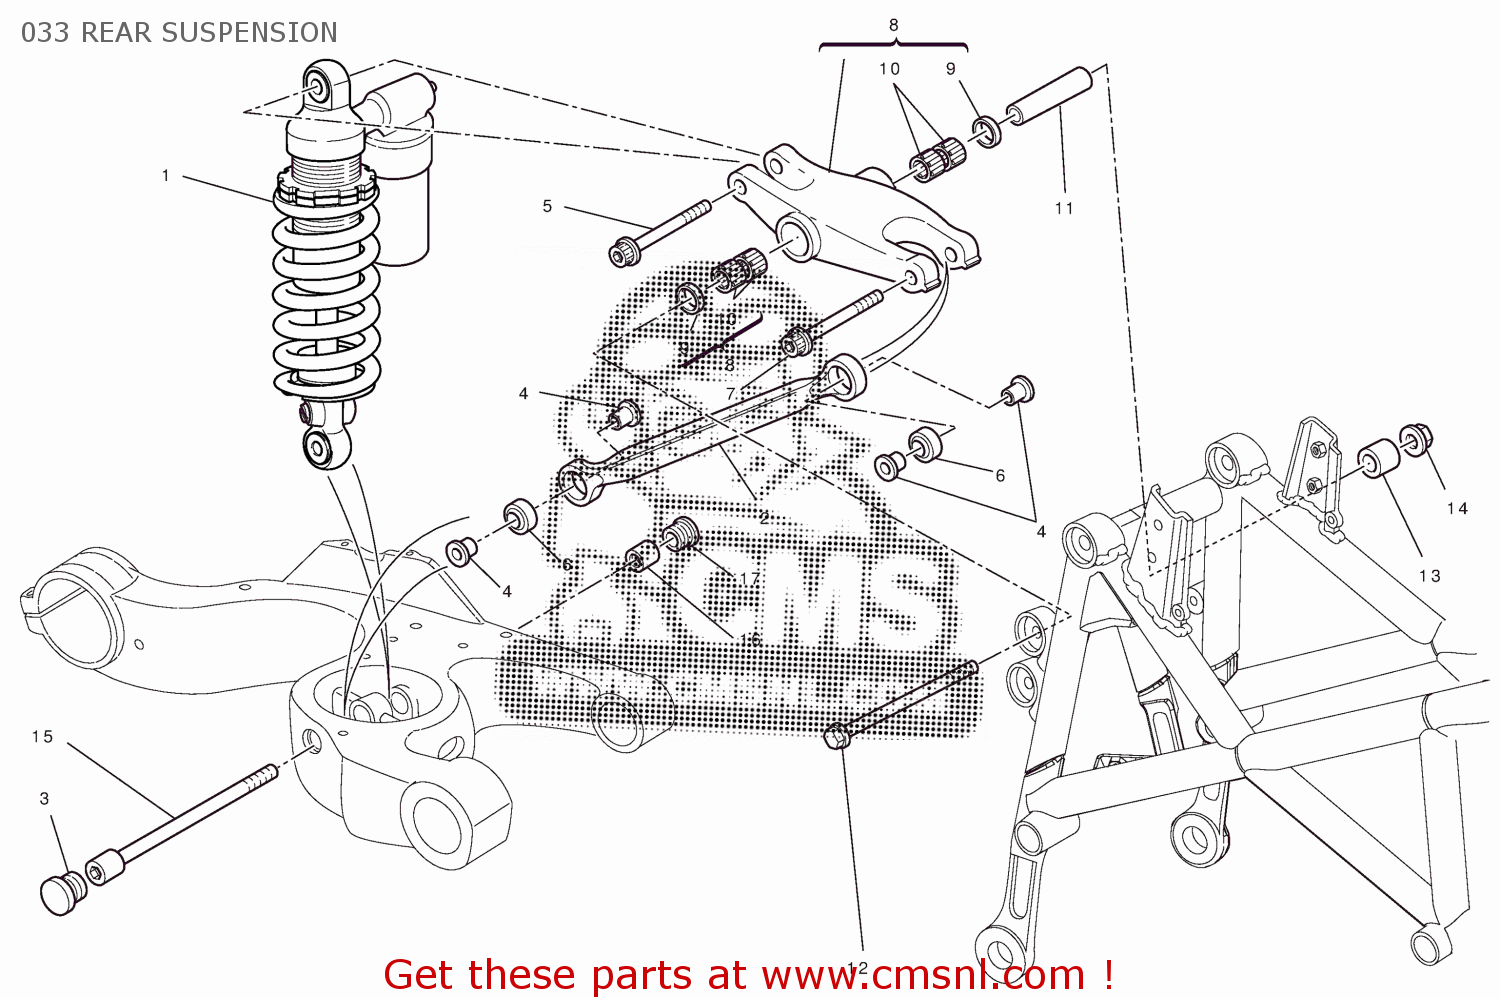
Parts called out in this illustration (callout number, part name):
1	REAR SHOCK ABSORBER
2	ROD
3	PLUG, RH
4	SPINDLE, TAPER
5	SCREW TCEIF M10X50X1.25
6	BALL JOINT
7	SCREW TCEIF M10X50X1.25
8	LEVER SET, REAR CUSHION
9	SEAL RING 18X24X3
10	BEARING, NEEDLE
11	SPACER
12	SCREW M10X1.25X127.5
13	SPACER
14	NUT M10X1.25X10
15	SCREW
16	NUT, SPECIAL
17	PLUG
